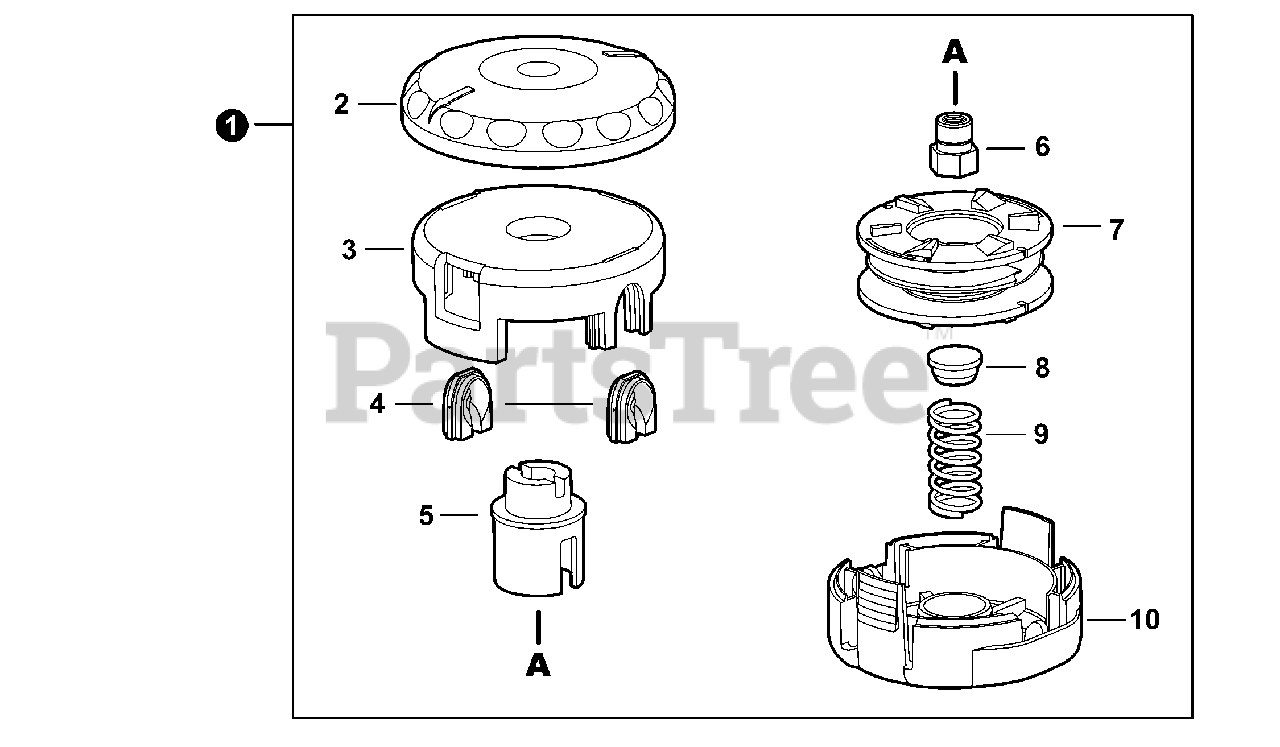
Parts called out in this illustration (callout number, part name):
1	TRIMMER HEAD, SPEED-FEED 375
3	HOUSING, SPOOL
5	HUB, SPOOL
6	BUSHING LH M10×1.25 FEMALE
7	SPOOL LH
8	CAP, SPRING
9	SPRING, COMPRESSION
10	COVER, SPOOL
